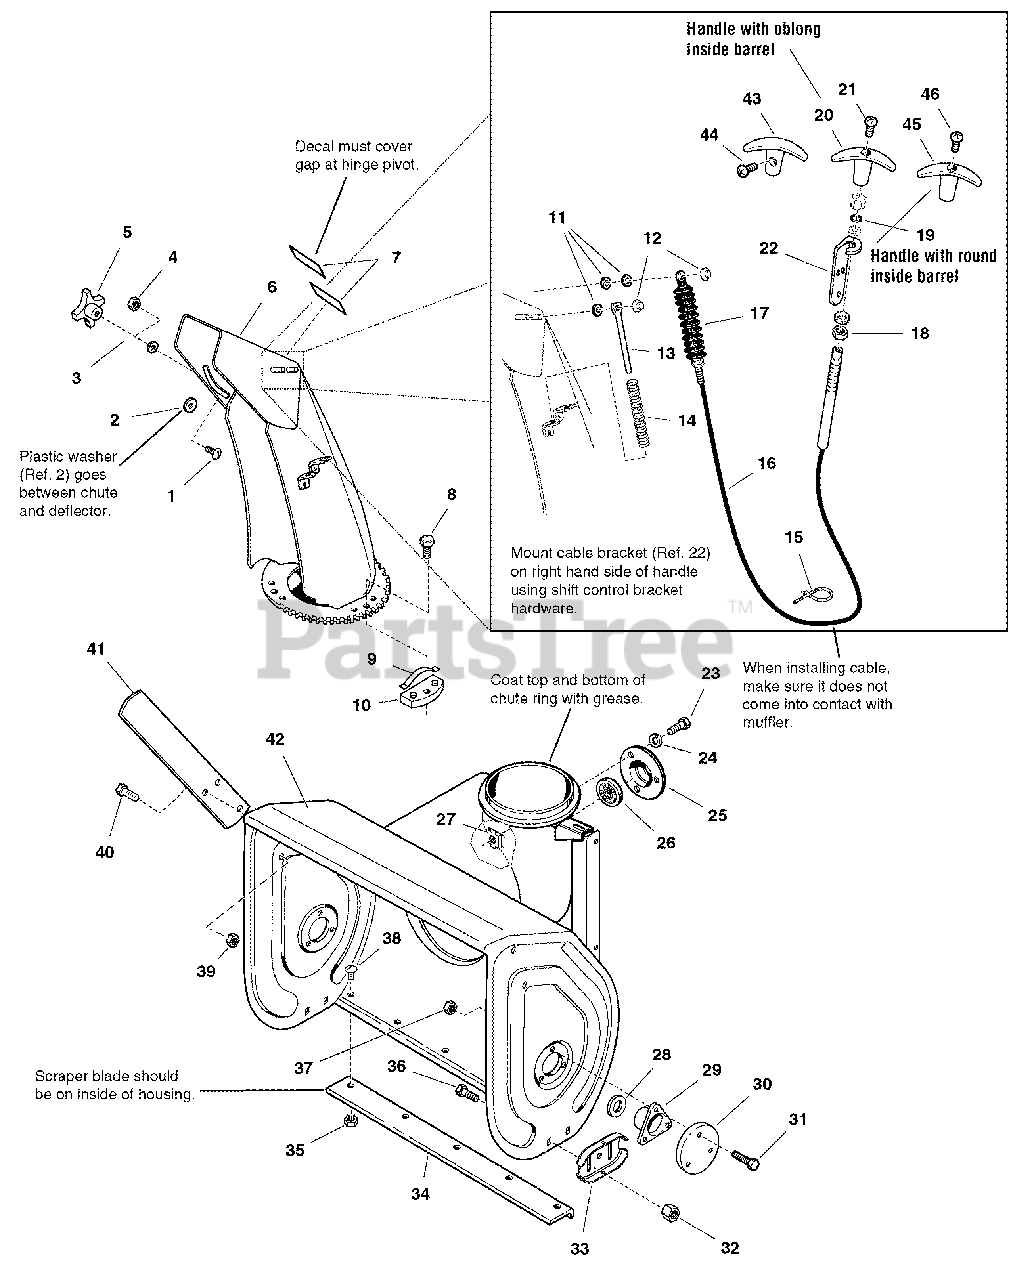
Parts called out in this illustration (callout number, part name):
1	CARRIAGE BOLT, 5/16-18 x 3/4 G5
2	WASHER, Nylon
3	WASHER, 5/16
4	NUT, Hex Lock ESNA Light, 5/16-18NC-3B (Used on all models Except 9560 Models)
5	KNOB, Internal Thread, 5/16 (Used Only on 9560 Models)
6	CHUTE AND DEFLECTOR ASSEMBLY, Manual (Used Only on 9560 Models)
6	CHUTE AND DEFLECTOR ASSEMBLY, w/Remote (Used on all models Except 9560 Models)
7	DECAL, Orange Strip
8	SCREW, Hex Washer Head Pastite, 10-14 x 5/8
9	SPRING, Flat
10	HOLD DOWN, Chute
11	SPACER, 17/64 ID x 3/8 OD
12	NUT, Push 1/4
13	ROD, Spring
14	SPRING, Compression
15	TIE, Self Locking (Used on all models Except 9560 Models)
16	CABLE AND KNOB ASSEMBLY, Chute (Includes Ref. No. 17, 18, 19, 20 & 21)
17	BOOT, Bellows
18	COLLET
19	SEAL, Rod
20	KNOB
21	SCREW, 8-32
22	BRACKET, Cable
23	CAPSCREW, Hex Head, 5/16-18 x 5/8 G5
24	LOCKWASHER, Spring, 5/16
25	RETAINER, Bearing
26	BEARING, Ball
27	NUT, Retainer Speed, 5/16-18
28	SPACER, Low
29	BEARING, Flange
30	CAP, Bearing, 3-3/4OD
31	CAPSCREW, Hex Head 5/16-18 x 7/8 G5
32	NUT, Hex Flange 3/8-16 ESNA
33	SKID SHOE, Reversible
34	BLADE, Scraper, 24" (Used Only on 9560 & 1060 Models)
34	BLADE, Scraper, 28" (Used Only on 1170 Models)
34	BLADE, Scraper, 32" (Used Only on 1280 Models)
35	NUT, Hex Flange, 5/16-18, Two-Way Lock GA (Quantity 7 Only on 1280 Models)
36	CARRIAGE BOLT, 3/8-16 x 3/4
37	NUT, Hex Centerlock, 5/16-18
38	CARRIAGE BOLT, 5/16-18 x 5/8 G5 (Quantity 7 Only on 1280 Models)
39	NUT, Hex Keps, 5/16-18, Conical Washer (Used on all models Except 9560 Models)
40	CAPSCREW, Hex Head, 5/16-18 x 3/4 G5 (Used on all models Except 9560 Models)
41	CUTTER, Drift, 1/4" Thick, 20LG (Used on all models Except 9560 Models)
42	HOUSING AND IMPELLER ASSEMBLY, 24" (Used on 9560 & 1060 Models)
42	HOUSING AND IMPELLER ASSEMBLY, 28" (Used on 1170 Models)
42	HOUSING AND IMPELLER ASSEMBLY, 32" (Used on 1280 Models)
44	SCREW, Set, Hex #10-24 x 3/8
45	HANDLE "T"
46	SCREW, Round Head
